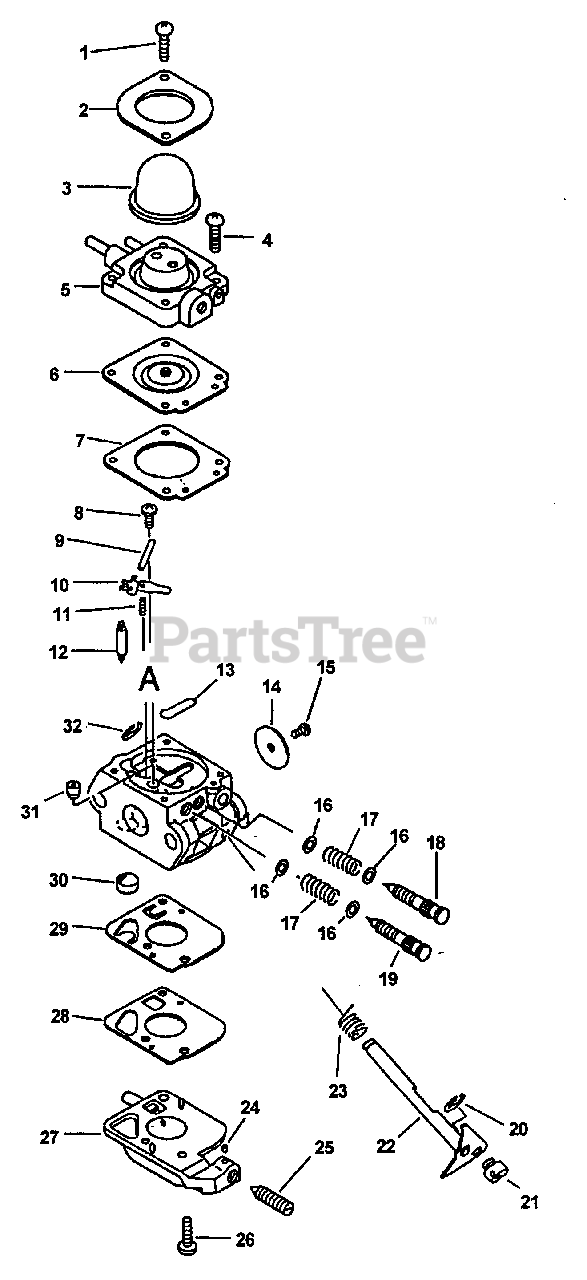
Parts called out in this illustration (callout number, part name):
1	SCREW, RETAINER
2	RETAINER, PURGE BULB
3	BULB, PURGE
4	SCREW, PURGE BASE
5	BASE, PURGE
6	DIAPHRAGM, METERING
7	GASKET, METERING DIAPHRAGM
8	SCREW, METERING LEVER PIN
9	BASE, PURGE
10	BASE, PURGE
10	REPAIR KIT
11	BASE, PURGE
12	BASE, PURGE
13	BASE, PURGE
14	VALVE, THROTTLE
18	NEEDLE - MIXTURE
19	NEEDLE - HIGH SPEED
20	RING, RETAINING
22	SHAFT, THROTTLE
23	SPRING, RETURN
24	PIECE, FRICTION
25	SCREW, IDLE ADJUST
26	SCREW, PUMP COVER
27	BASE, PURGE
28	GASKET, FUEL PUMP
29	DIAPHRAGM, PUMP
30	STRAINER
30	REPAIR KIT
31	NOZZLE, CHECK VALVE
32	RING, RETAINING
A	REPAIR KIT
B	DIAPHRAGM/GASKET KIT
